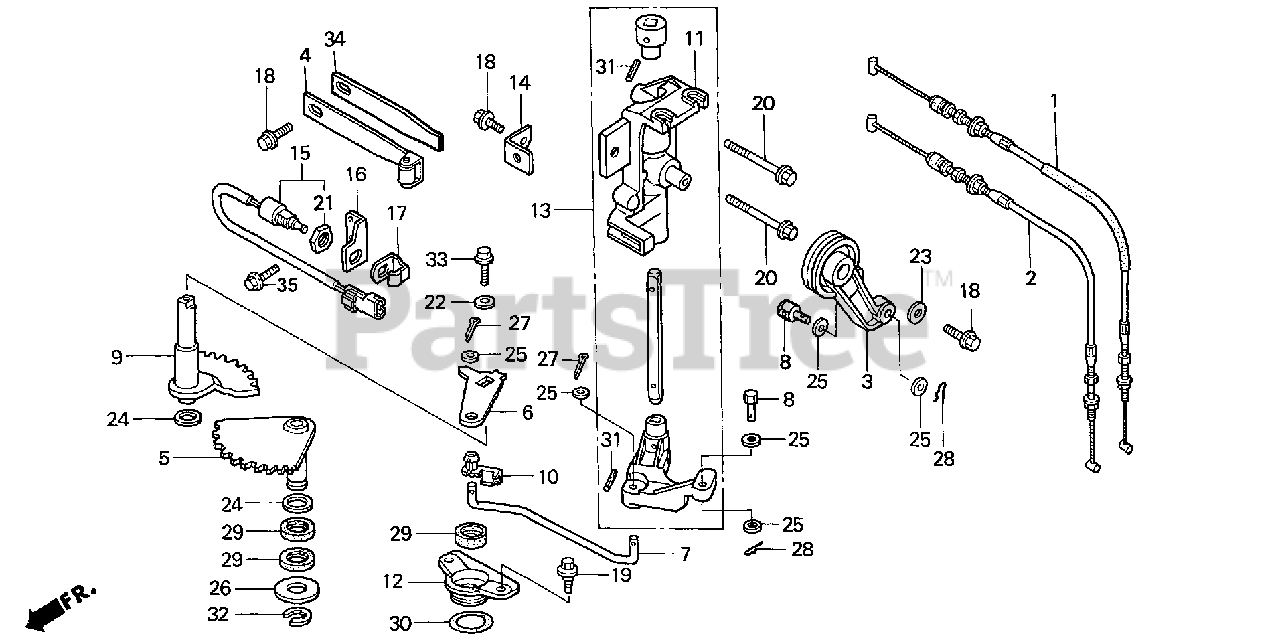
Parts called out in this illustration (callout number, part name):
1	CABLE A, THROTTLE
2	CABLE B, THROTTLE
3	ARM, THROTTLE
4	SPRING, CLICK
5	SHAFT, SHIFT (A)
6	ARM, SHIFT
8	PIVOT, SHIFT
9	SHAFT, SHIFT (B)
10	BUSH, SHAFT
11	BRACKET, SHIFT LINK *NH8* (DARK GRAY)
12	HOLDER, SEAL
13	LINK, SHIFT
14	BRACKET, CLIP (D)
15	SWITCH ASSY., NEUTRAL
16	BRACKET, NEUTRAL SWITCH
17	PLATE, NEUTRAL SWITCH
18	BOLT, FLANGE (6X12)
19	BOLT, FLANGE (6MM)
19	BOLT, FLANGE (6X11)
20	BOLT, FLANGE (6X42)
21	NUT, HEX. (20MM)
22	WASHER (6MM)
23	WASHER (6MM)
24	WASHER, SHIFT SHAFT
25	WASHER, PLAIN (6MM)
27	PIN, SPLIT (2.0)
28	PIN, LOCK SPECIAL (6MM)
29	OIL SEAL (14X26X6)
30	O-RING (26.9X2.4) (NOK)
31	PIN, SPRING (3X18)
32	E-RING (12MM)
33	BOLT, FLANGE (6X12)
34	SPRING, CLICK ASSIST
35	BOLT, FLANGE (6X12)
35	BOLT, FLANGE (6X14) (CT200)
